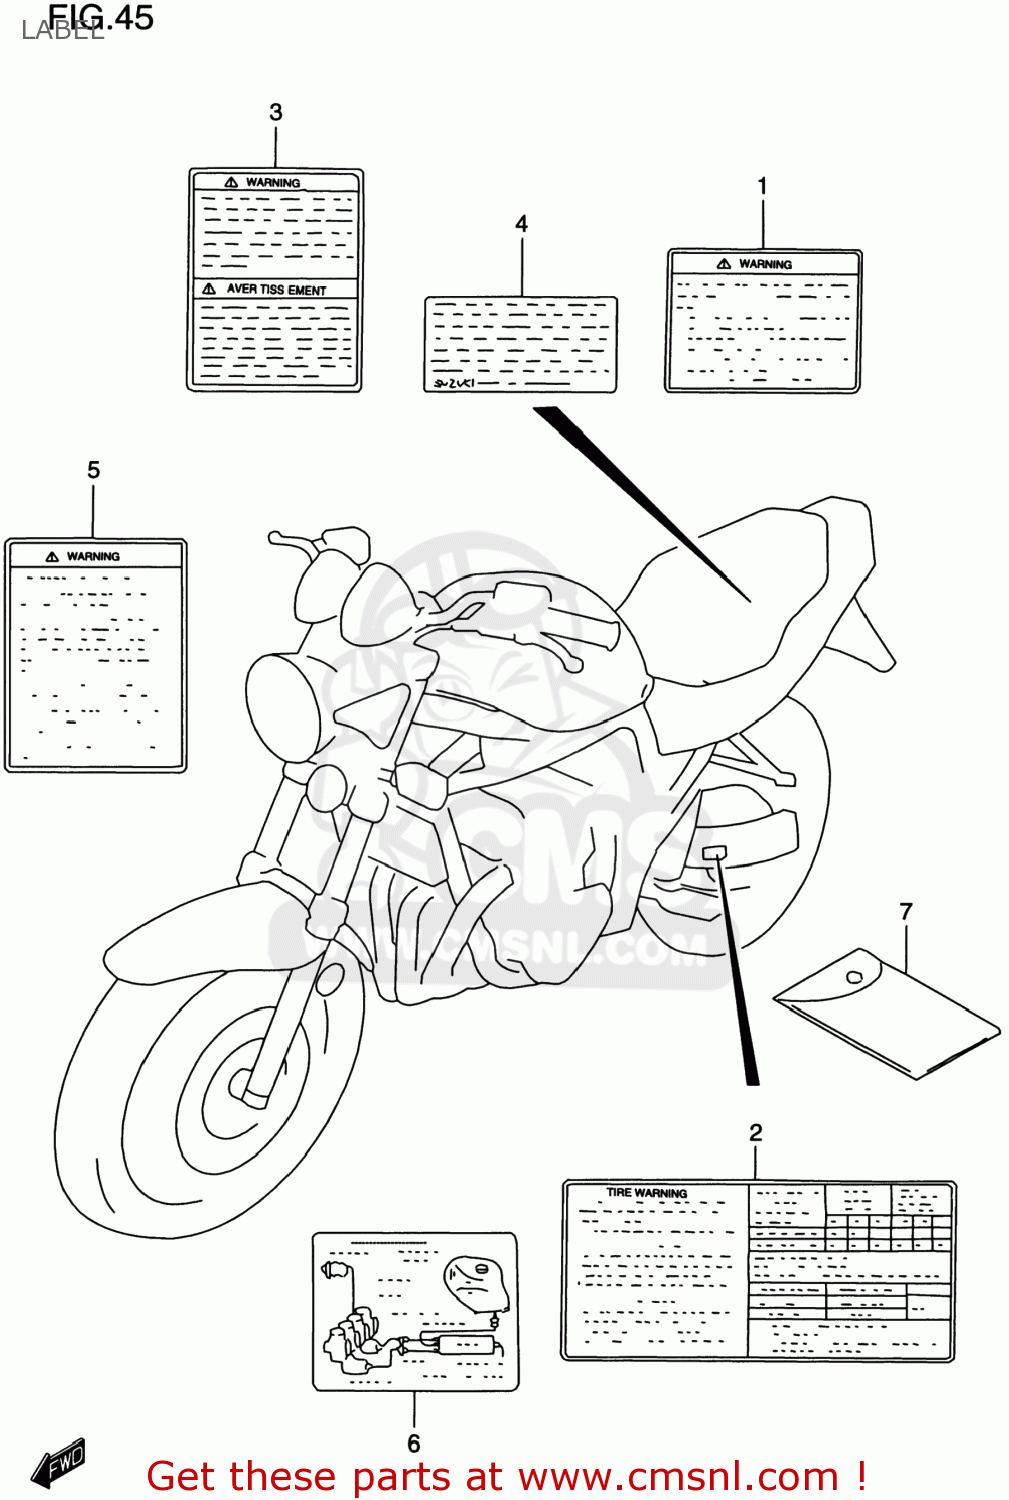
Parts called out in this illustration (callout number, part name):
1	LABEL,GENERAL WARNING
2	LABEL (TIRE AIR PRESSURE)
3	LABEL,WARNING STEERING
4	LABEL (MANUAL NOTICE)
5	LABEL,WARNING SCREEN
6	LABEL,VACUUM HOSE ROUTING
7	BAG COMP,OWNERS MANUAL
8	MANUAL, OWNER'S
